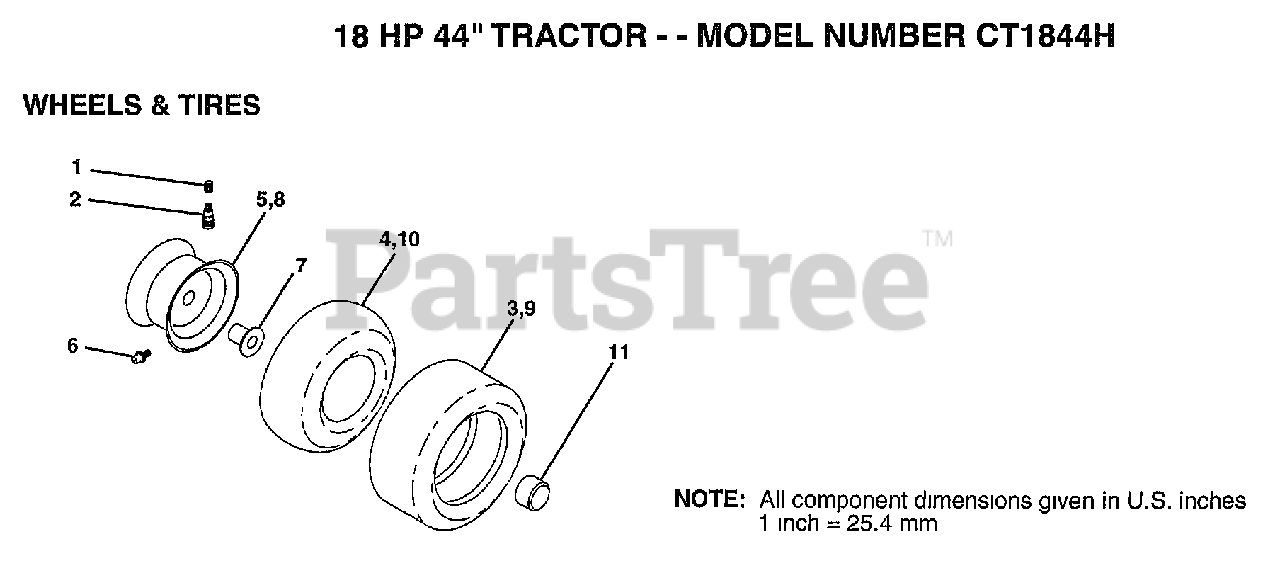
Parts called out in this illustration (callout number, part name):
1	VALVE CAP
2	VALVE STEM LT
4	TUBE.5.3/4.5/6
5	"RIM ASM 8"" FRT"
6	FITTING LT
7	"FLANGE, BEARING"
8	RIM.REAR.
10	TUBE.23X8/10-12
11	HUB CAP
